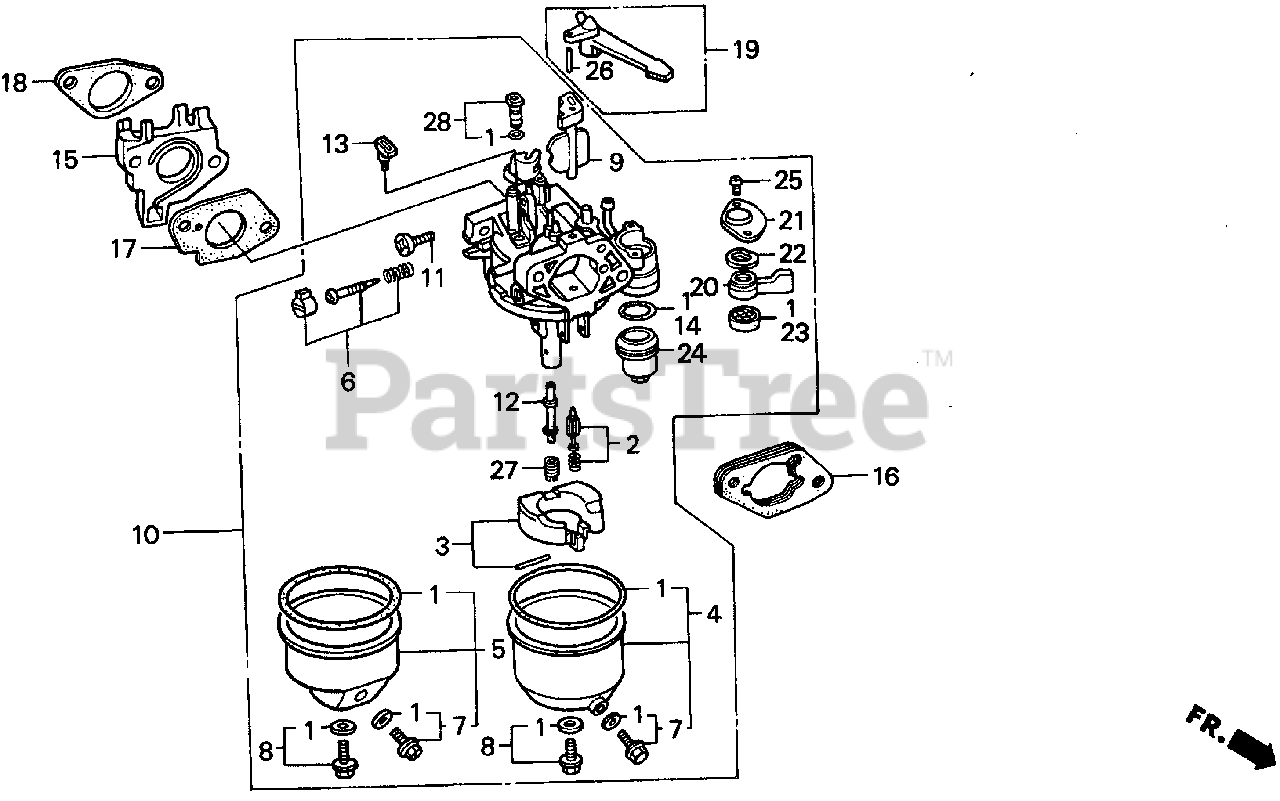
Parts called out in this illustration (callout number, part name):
1	GASKET SET
2	VALVE SET, FLOAT
3	FLOAT SET
4	CHAMBER SET, FLOAT
5	CHAMBER SET, FLOAT
6	SCREW SET
7	SCREW SET, DRAIN
8	SCREW SET B
9	CHOKE SET
10	CARBURETOR ASSY. (BE85B B)
11	SCREW, THROTTLE STOP
12	NOZZLE, MAIN
13	COLLAR, SET
14	GASKET, FUEL STRAINER CUP
15	INSULATOR, CARBURETOR
16	SPACER, CARBURETOR
17	GASKET, CARBURETOR
18	GASKET, INSULATOR
19	LEVER, CHOKE (STD)
20	LEVER, VALVE
21	PLATE, LEVER SETTING
22	SPRING, VALVE LEVER
23	GASKET, VALVE
24	CUP, FUEL STRAINER
25	SCREW, PAN (3X6)
25	SCREW, PAN (3X8)
26	PIN, SPRING (2X12)
27	JET, MAIN (#88)
27	JET, MAIN (#90)
27	JET, MAIN (#92)
28	JET SET, PILOT (#45)
